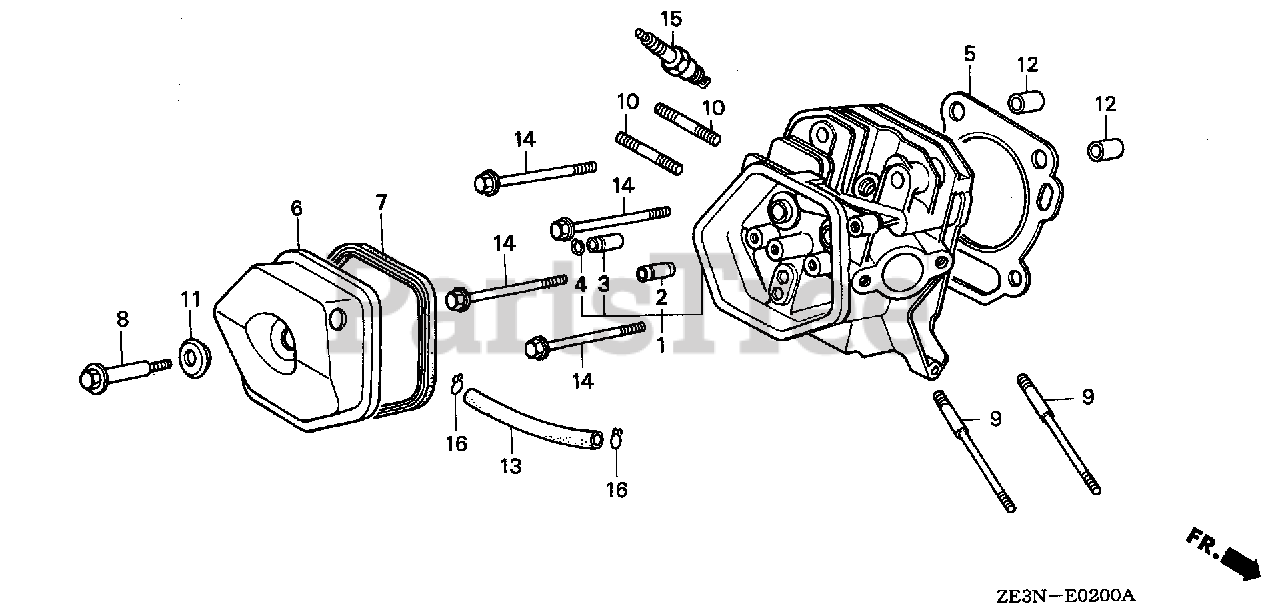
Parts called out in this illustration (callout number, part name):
1	CYLINDER HEAD
2	GUIDE, VALVE (OS)
3	GUIDE, EX. VALVE (OS)
4	CLIP, VALVE GUIDE
5	GASKET, CYLINDER HEAD
6	COVER, HEAD
7	GASKET, CYLINDER HEAD COVER
8	BOLT, HEAD COVER
9	BOLT, STUD (8X131.5)
10	BOLT, STUD
10	BOLT 2, STUD (8X32)
11	WASHER, HEAD COVER
12	PIN A, DOWEL (12X20)
13	BULK HOSE, VACUUM (11X1000) (11X105)
14	BOLT, FLANGE (10X80)
15	SPARK PLUG (BPR5ES) (NGK)
15	SPARK PLUG (W16EPR-U) (DENSO)
15	SPARK PLUG (BPR6ES) (NGK)
15	SPARK PLUG (W20EPR-U) (DENSO)
